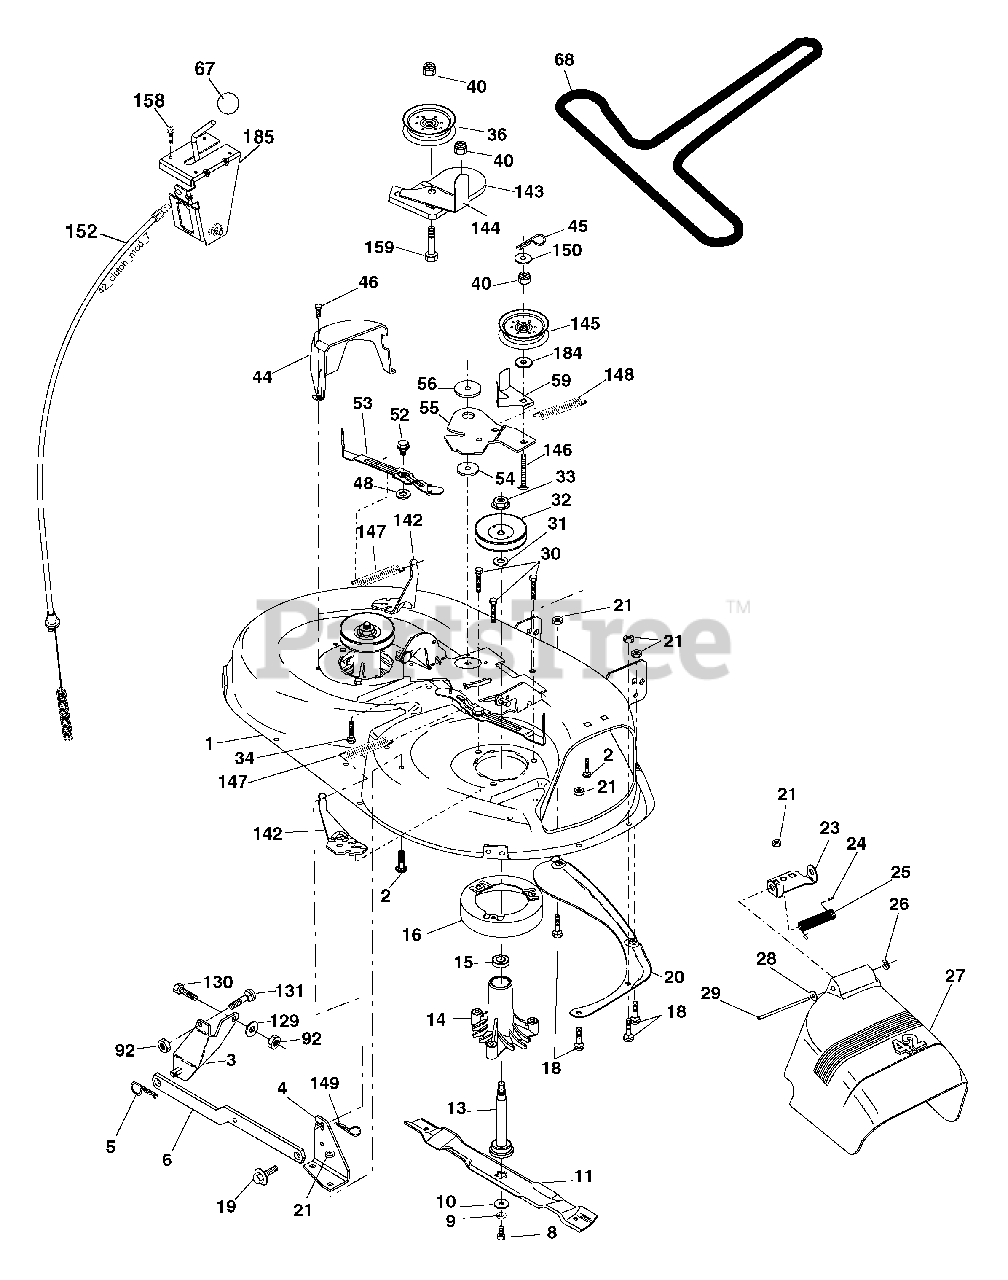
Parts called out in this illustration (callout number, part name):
1	Mower Deck Assembly, 42"
2	Bolt
3	Bracket Asm Fr. Sway Bar 3/42
4	Bracket Asm Deck 42" Sway Bar
5	Retainer Spring
6	Bar Sway Deck
8	Bolt 3/8-24 x 1.25 Gr. 8 patched
9	Washer, Lock
10	Washer, Hardened (The following Blades are available)
11	Blade Mower 42" Hi-Lift (for bagging and discharging)
11	Blade, Mulching 42" Std (for mulching mowers only)
11	Blade Mulching 42" Premium (For better wear when mulching)
13	Shaft Assembly, Mandrel, Vented
14	Housing, Mandrel, Vented
15	Bearing, Ball, Mandrel
16	Stripper, Mandrel Deck
18	Bolt, Carriage 5/16-18 x 5/8
19	Bolt, Shoulder
20	Baffle, Vortex
21	Nut
23	Bracket, Deflector Mower 42"
24	Cap, Sleeve 80 x 112 Blk Mower
25	Spring, Torsion, Deflector 2 52
26	Nut, Push Phos & Oil
27	Shield, Deflector 42" Blk
28	Washer 11/32 x 5/8 x 16 Ga.
29	Rod, Hinge 42" 6 75 W/G
30	Screw Thdrol
31	Washer, Spacer Mower Vented
32	Pulley, Mandrel
33	Nut, Toplock
34	Bolt Carr SH 3/8-16 x 1-1/2 Gr.5
36	Pulley, Idler, Flat
40	Nut Lock 3/8-16
44	Guard, Mandrel, LH
45	Retainer
46	Screw, Thdrol 1/4-20 x 5/8 T
48	Washer, Hardened
52	Bolt, Shoulder 5/16-18 unc
53	Arm Assembly, Pad, Brake
54	Washer, Hardened
55	Arm, Idler
56	Spacer, Retainer
59	Guard TUV Idler
67	Knob Round
68	V-Belt, 42" Mower
92	Locknut, Hex, with Insert 3/8-16
129	Washer 13/32 x 13/16 x 12 Gauge
130	Bolt, Hex Head 3/8-16 x 1 Grade 5
131	Bolt, Carriage 3/8-16 x 1
142	Arm Spring Brake Mower
143	Bracket Arm Idler 42"
144	Keeper Belt 42" Clutch Cable
145	Pulley Idler Flat
146	Bolt Carriage Idler
147	Spring Extension
148	Spring Return Idler
149	Retainer Spring Yellow
150	Washer 9/32 x 3/4 x 10 Ga.
152	Clutch Cable 42"
158	Screw Hex Thd Cut 1/4-20 x 1/2
159	Bolt Rdhd Sqn 3/8-16 unc x 1-3/4
184	Washer 13/32 x 7/8 x 10 Ga.
185	Head Asm Cable Clutch
